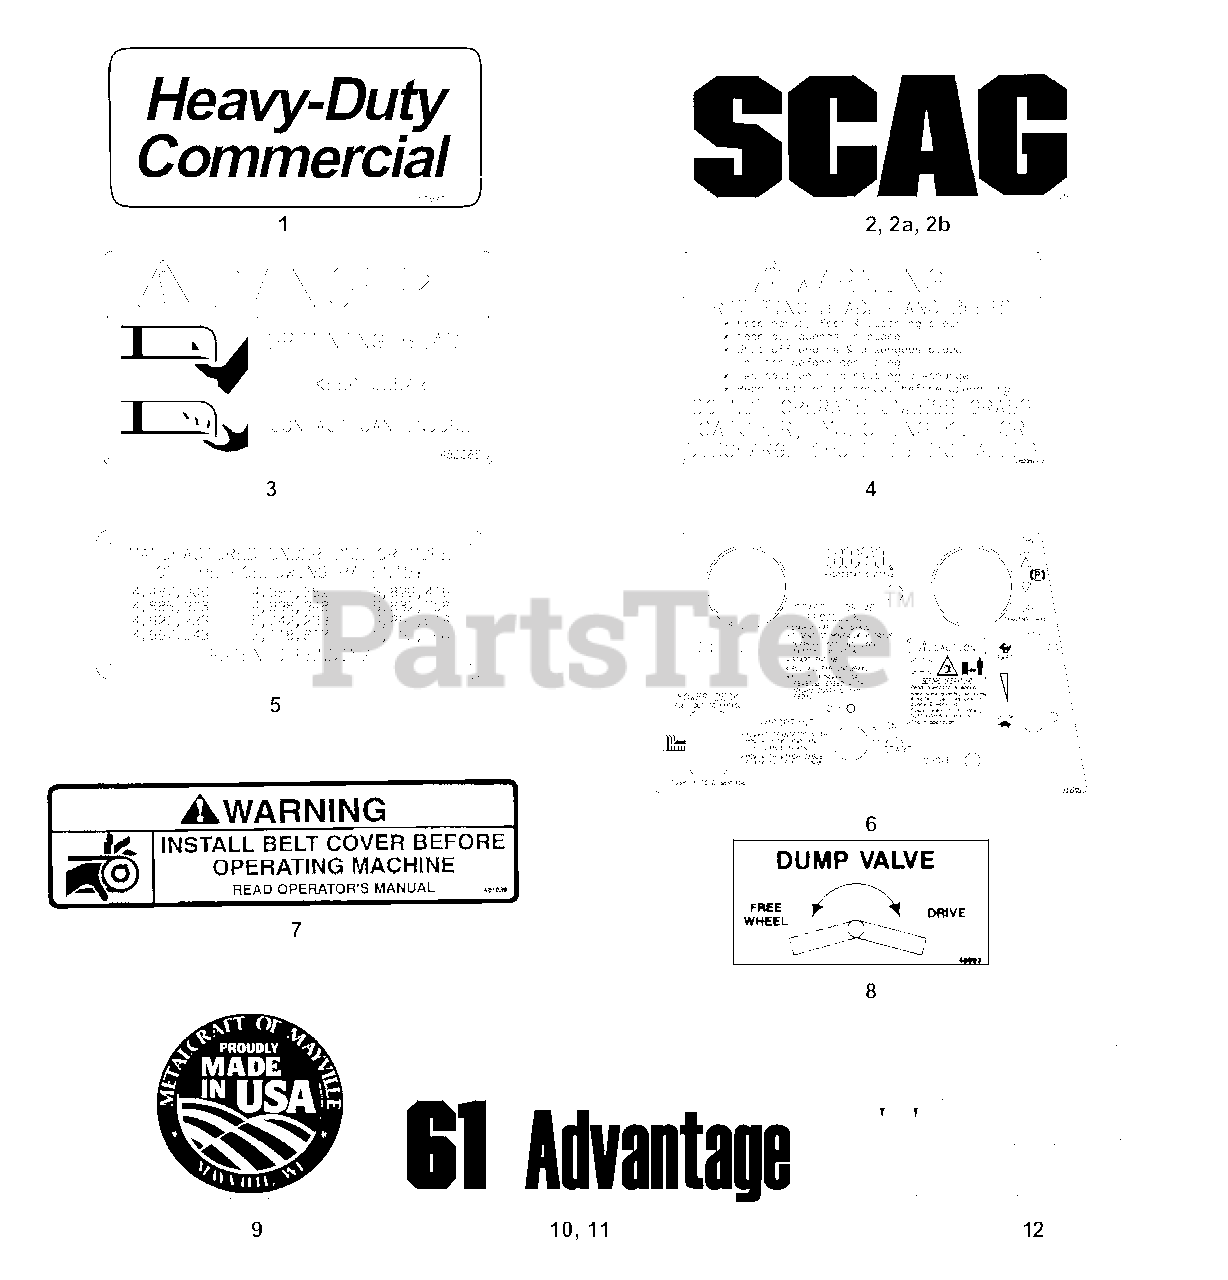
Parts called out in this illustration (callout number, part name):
1	Decal, Heavy Duty Commercial
2	Decal, Scag Logo (Cutter Deck)
2A	Decal, Scag Logo (Battery Box Front)
2B	Decal, Scag Logo Seat Back
3	Decal, Danger-Spinning Blades
4	Decal, Warning-Rotating Blades
5	Decal, Patent
6	Decal, Instrument Panel
7	Decal, Warning-Belt Cover
8	Decal, Dump Valve
9	Decal, Metalcraft-Made In USA
10	Decal, 61 Advantage
11	Decal, 72 Advantage
12	Decal, Height of Cut
